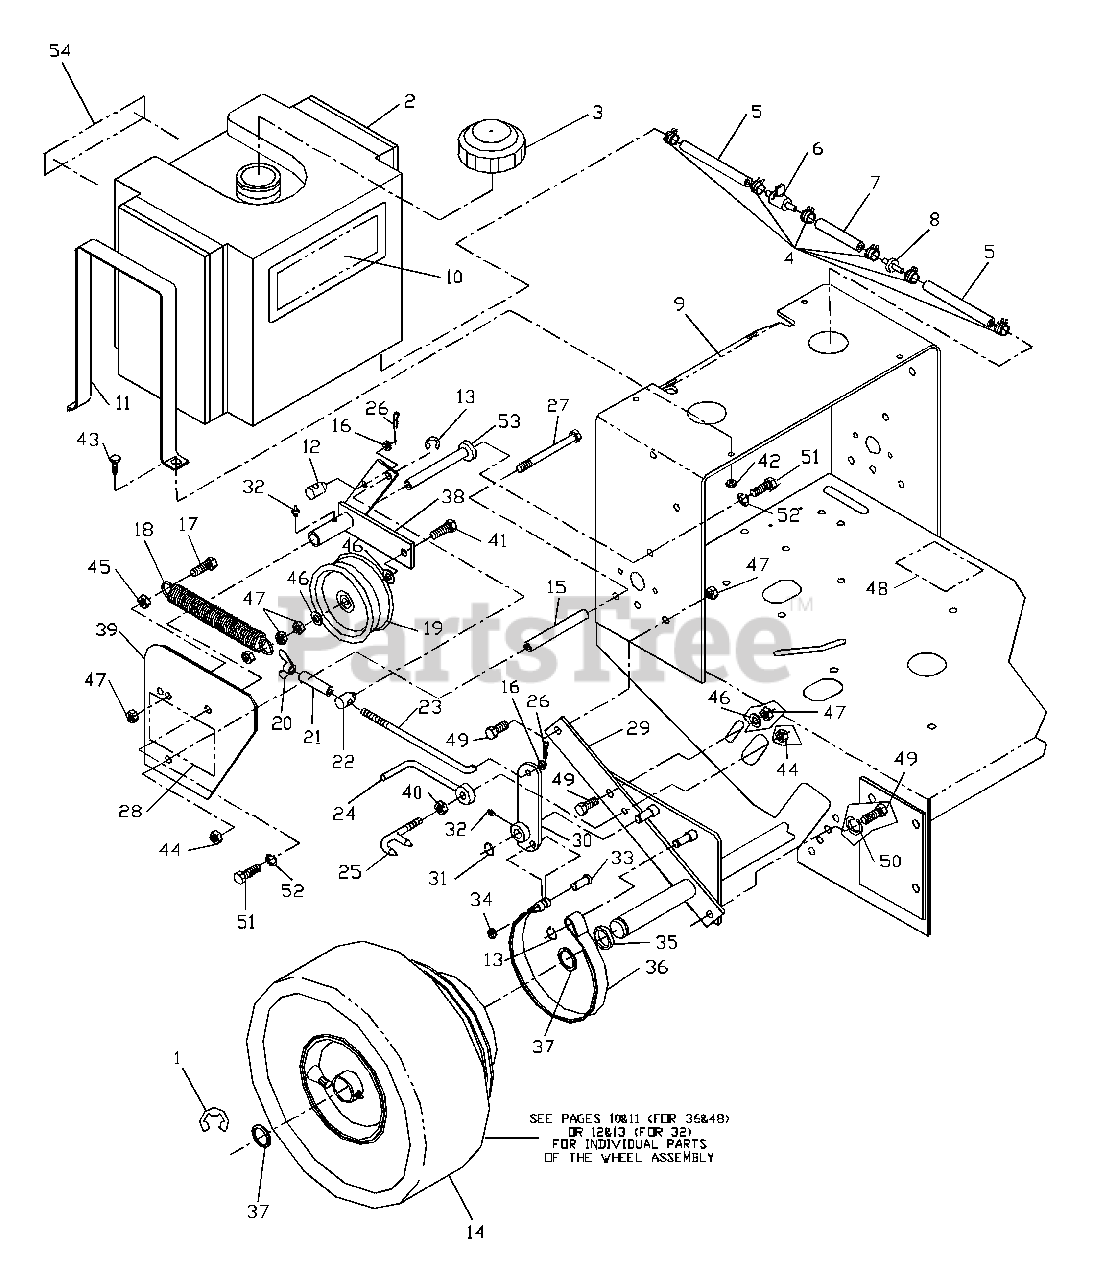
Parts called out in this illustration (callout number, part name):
1	1" E-RING
4	HOSE CLAMP
5	10" GAS LINE
6	FUEL VALVE
7	3 1/2" GAS LINE
7	14" GAS LINE
8	FUEL FILTER
9	REAR DECK W/DECALS
10	DECAL, W3212
10	DECAL, W3213
10	DECAL, W3612
10	DECAL, W3613
10	DECAL, W3614
10	DECAL, W4814
10	DECAL, W4815
11	TANK STRAPS
12	SWIVEL (SHORT)
13	3/8" E-RING
14	WHEEL ASM.
15	LONG SPACER
16	5/16 FW STD
17	HCS 3/8C X 1 1/4
19	IDLER PULLEY
20	5/16C NYLOC WING NUT
24	BELT GUIDE
25	SCRAPER
26	#2 HAIRPIN
27	HCS 5/16C X 5
28	DECAL, SMALL CROWN
29	AXLE WLDMT
30	RT. BRAKE ARM
30	LT. BRAKE ARM
31	1/2' E-RING
32	ZERK 1/4-28 STRHT
33	CLEVIS PIN
34	BOLT RETAINER 3/8
36	BRAKE BAND
37	MACH. BUSHING
38	IDLER PLATE, LT
38	IDLER PLATE, RT
40	HFLN 5/16C
41	3/8C X 3 TAP BOLT
43	HCS 1/4C X 1
46	FW 3/8 STD
47	HLN 3/8C CENTER P.
48	DECAL, PROP. 65
49	HCS 3/8C X 1
50	SLW 3/8 STD
51	HCS 5/16C X 1
52	SLW 5/16 STD
53	SHOULDER PIVOT TUBE
54	DECAL, HUSQVARNA
